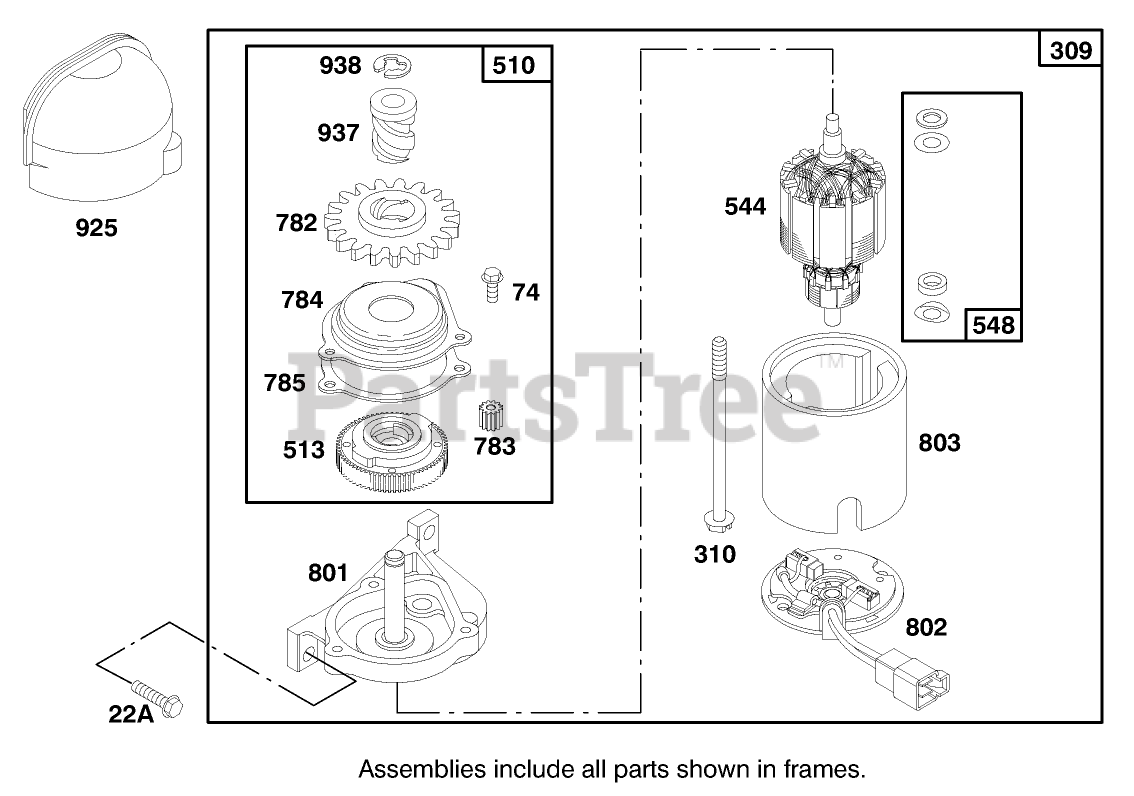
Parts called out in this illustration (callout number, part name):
22A	SCREW - CARBUERTOR MTG
74	SCREW - SEM
510	DRIVE SET
513	CLUTCH - STARTER
548	WASHER ASSEMBLY
782	GEAR - STARTER
925	COVER - STARTER
938	RETAINER - LOCK
